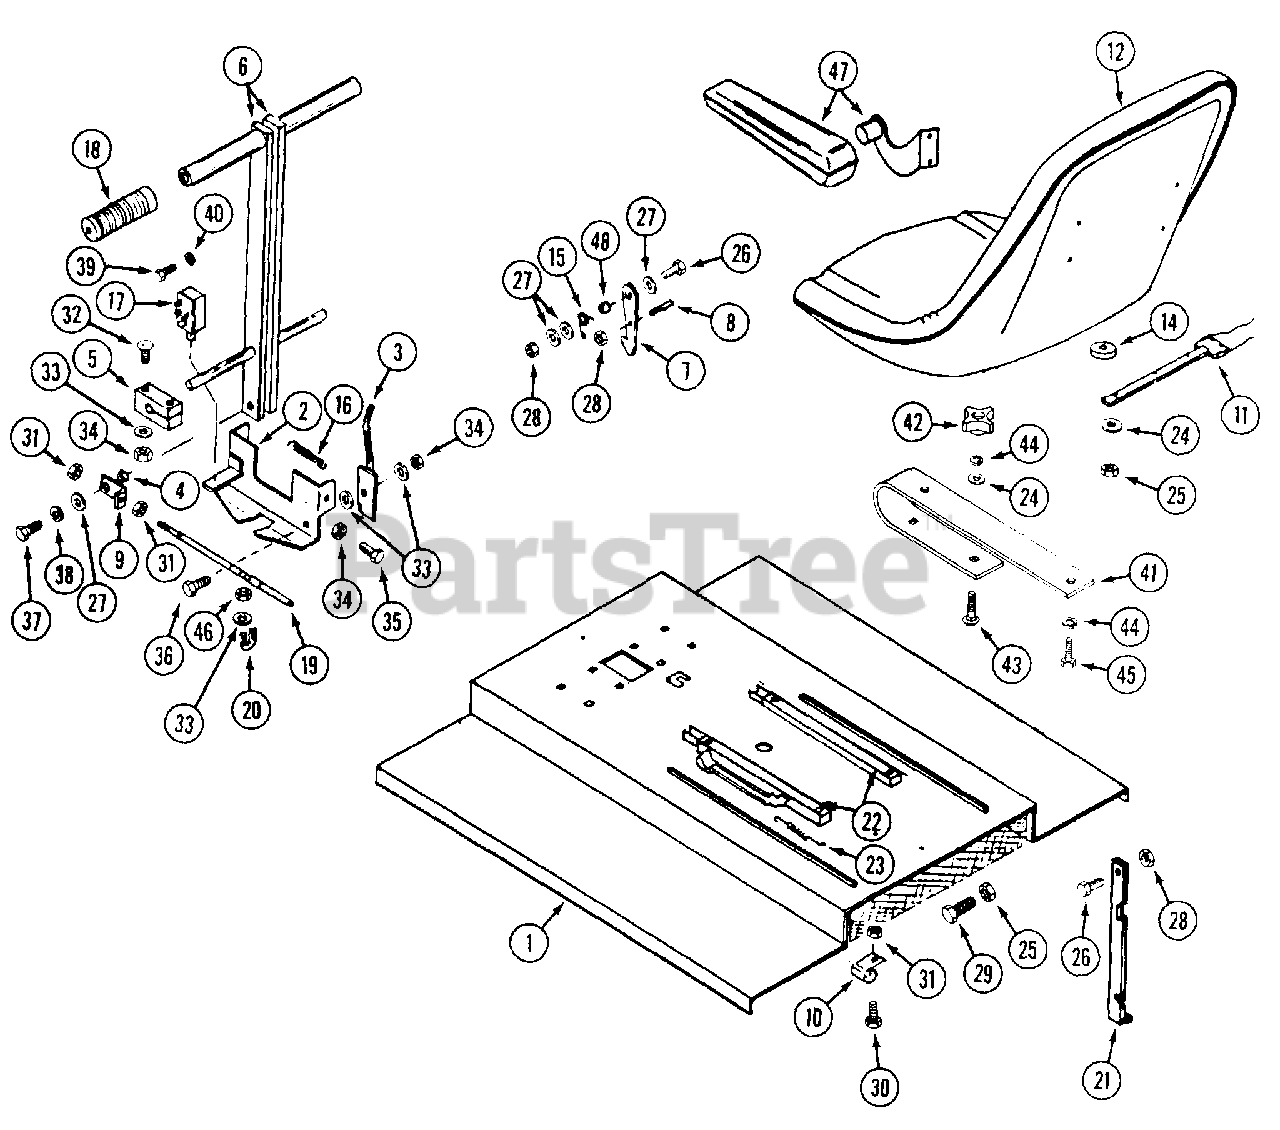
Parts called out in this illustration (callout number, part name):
1	LID - seat
2	BRACKET - lever lock
3	LATCH - lever lock
4	BUSHING
5	BEARING - block
6	LEVER - steering
7	LATCH - seat lid
8	BOLT - latch, seat lid
9	BRACKET - steering cable end
10	RETAINER - harness, seat lid
12	SEAT
15	SPRING - latch, seat lid
16	SPRING - bracket, lever lock
17	SWITCH - safety
18	GRIP - handle
19	CABLE - steering
20	CLAMP - steering cable
21	PROP - seat lid
22	KIT - seat slide rail (pair)
24	WASHER - 5/16"
25	NUT - 5/16"
26	BOLT - 1/4"-20 x 1"
27	WASHER - 1/4"
28	NUT - 1/4"-20 lock
29	BOLT - 5/16"-18 x 1"
30	SCREW - #10-32 x 1/2"
32	BOLT - 1/4"-20 x 1-1/2" carriage
33	WASHER - 1/4"
34	NUT - 1/4"-20 lock
35	BOLT - 1/4"-20 x 3/4"
36	BOLT 1/4"-20 x 2"
37	BOLT - 1/4"-20 x 3/4"
38	LOCKWASHER - 1/4"
39	SCREW - #10-32 x 3/8"
40	LOCKWASHER - 3/16"
41	SPRING - seat
43	BOLT - carriage 5/16"-18 x 1-1/4"
44	LOCKWASHER - 5/16"
45	BOLT - 5/16"-18 x 1"
46	NUT - 1/4"-20
47	KIT - arm rest
